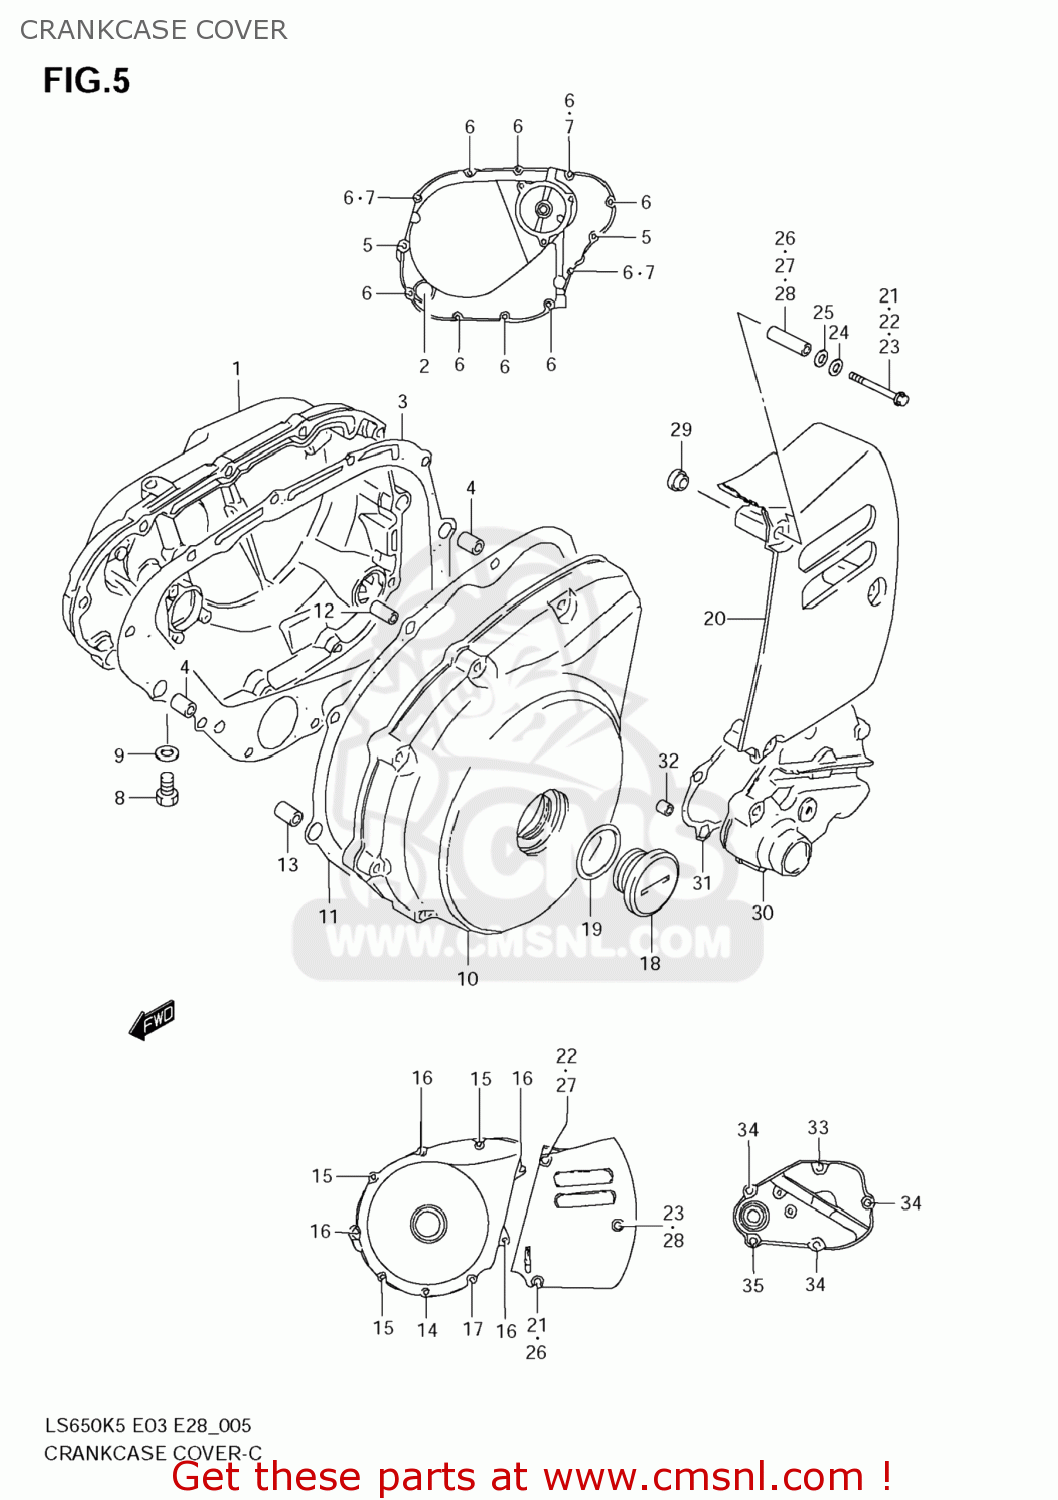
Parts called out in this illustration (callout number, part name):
1	COVER,CLUTCH
2	LENS,OIL LEVEL CHECK
3	GASKET,CLUTCH COVER (NAS)
4	PIN
5	BOLT(6X35)
6	BOLT(6X25)
7	GASKET(5.8X13X1.2) (NAS)
8	PLUG,12X9
9	GASKET(12.1X16.2X3.7) (NAS)
10	COVER,GENERATOR
11	GASKET,GENERATOR COVER (NAS)
12	PIN
13	PIN
14	BOLT(6X25)
15	BOLT(6X35)
16	BOLT(6X45)
17	BOLT(6X50)
18	PLUG,36X10
19	O RING(D:3.1,ID:32.7)
20	COVER,ENGINE SPROCKET
21	BOLT(6X45)
22	BOLT(6X50)
23	BOLT(6X55)
24	WASHER(6.5X14X1.6)
25	WASHER(8.7X15X2.1)
26	SPACER(6.5X9X31.5)
27	SPACER(6.5X9X38.3)
28	SPACER(6.5X9X41.3)
29	WASHER(8.7X16X5)
30	COVER,GEAR SHIFT
31	GASKET,GEAR SHIFT COVER (NAS)
32	PIN
33	BOLT
34	BOLT
35	BOLT
